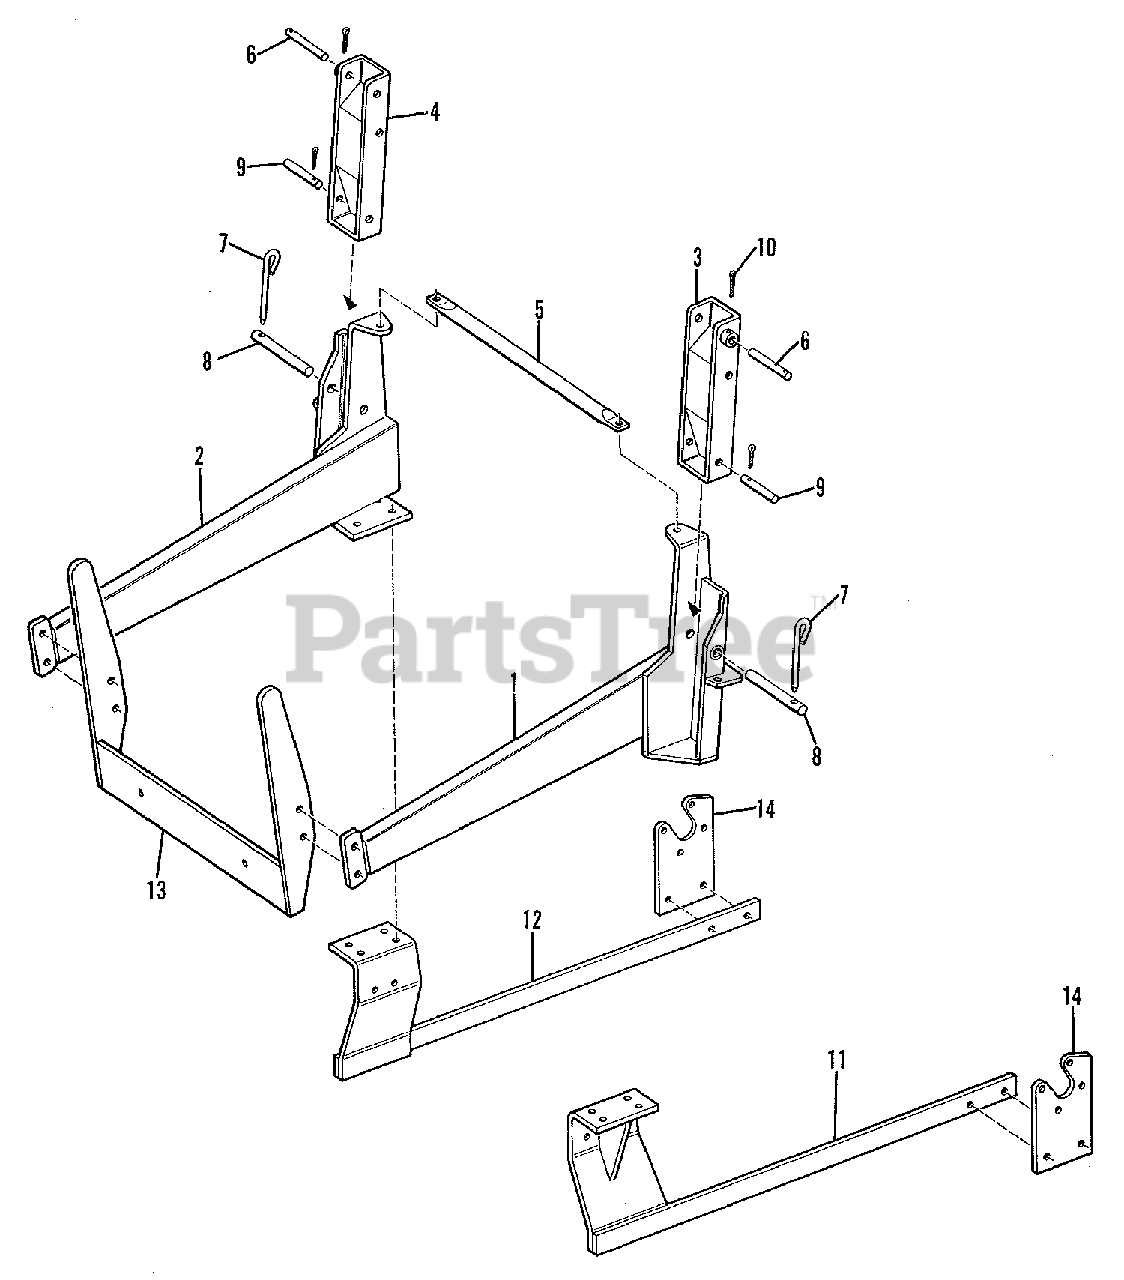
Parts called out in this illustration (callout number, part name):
1	FRAME ASSEMBLY, L.H.
1	CAPSCREW, 1/2NC x 1-1/2
1	LOCKWASHER, 1/2
2	FRAME ASSEMBLY, R.H.
2	CAPSCREW, 1/2NC x 1-1/2
2	LOCKWSHER, 1/2
3	SUPPORT ASSEMBLY, L.H.
3	CAPSCREW, 1/2NC x 1-1/2
3	LOCKWASHER, 1/2
4	SUPPORT ASSEMBLY, R.H.
4	CAPSCREW, 1/2NC x 1-1/2
4	LOCKWASHER, 1/2
5	BRACE, Cross
5	CAPSCREW, 1/2NC x 1-1/2
5	LOCKWASHER, 1/2
6	PIN, Boom Pivot
7	PIN, Locking, Support Assembly
8	PIN, Attaching, Support Assembly
9	PIN, Cylinder, Rear
10	PIN, Retaining
11	PAD ASSEMBLY, L.H. Mouting
11	CAPSCREW, Attaching
11	LOCKWASHER, 9/16
12	PAD ASSEMBLY, R.H. Mouting
12	CAPSCREW, Attaching
12	LOCKWASHER, 9/16
13	SUPPORT ASSEMBLY, Front
14	BRACKET, Axle Mounting
14	CAPSCREW, Attaching
14	LOCKWASHER, 1/2
14	U-BOLT, Axle Mounting
